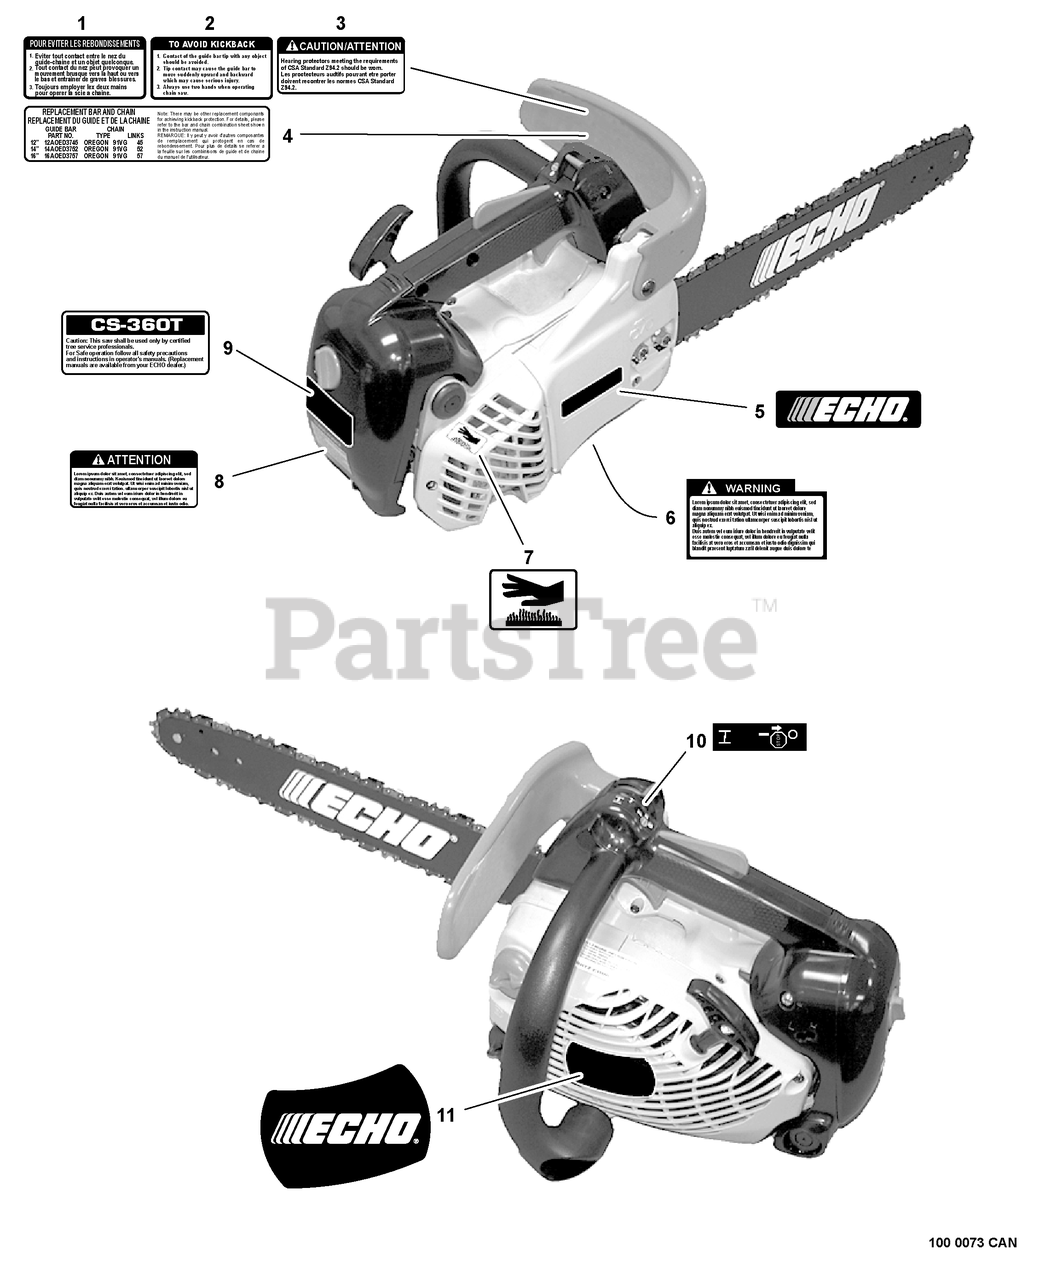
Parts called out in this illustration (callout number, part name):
1	LABEL - KICK BACK
2	LABEL - KICK BACK
3	LABEL - NOISE
4	LABEL - BAR & CHAIN
5	LABEL - ECHO
6	LABEL - WARNING
7	LABEL - HOT SURFACE
8	LABEL - CAUTION
9	LABEL - MODEL CS-360T
10	LABEL - STOP
11	LABEL - ECHO
